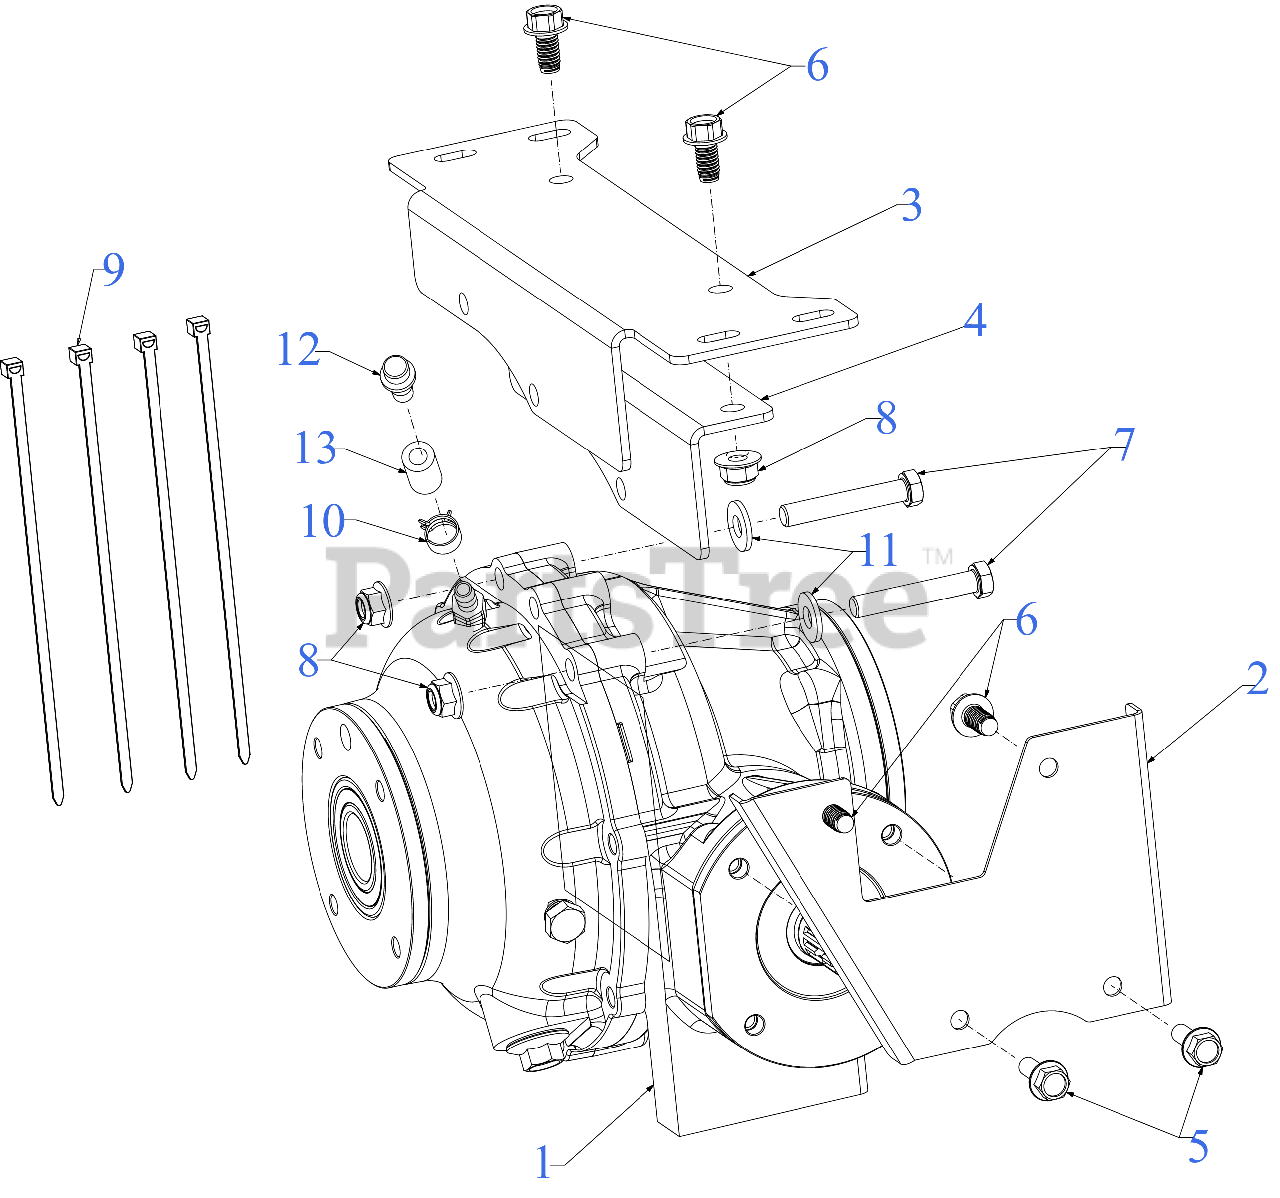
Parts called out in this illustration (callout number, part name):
1	DIFFERENTIAL ASSEMBLY
2	DIFFERENTIAL BRACKET
3	REAR DIFFERENTIAL MOUNT
4	REAR DIFFERENTIAL BRACKET
5	SCREW M8 x 1.25 x 25MM GR8.8
6	SCREW 3/8-16 x 3/4
7	SCREW 3/8-16 x 2.25 GR5
9	7" CABLE TIE
10	HOSE CLAMP
11	FLAT WASHER .385X.870X.090
13	FUEL HOSE LOW PERMEATION 22"
